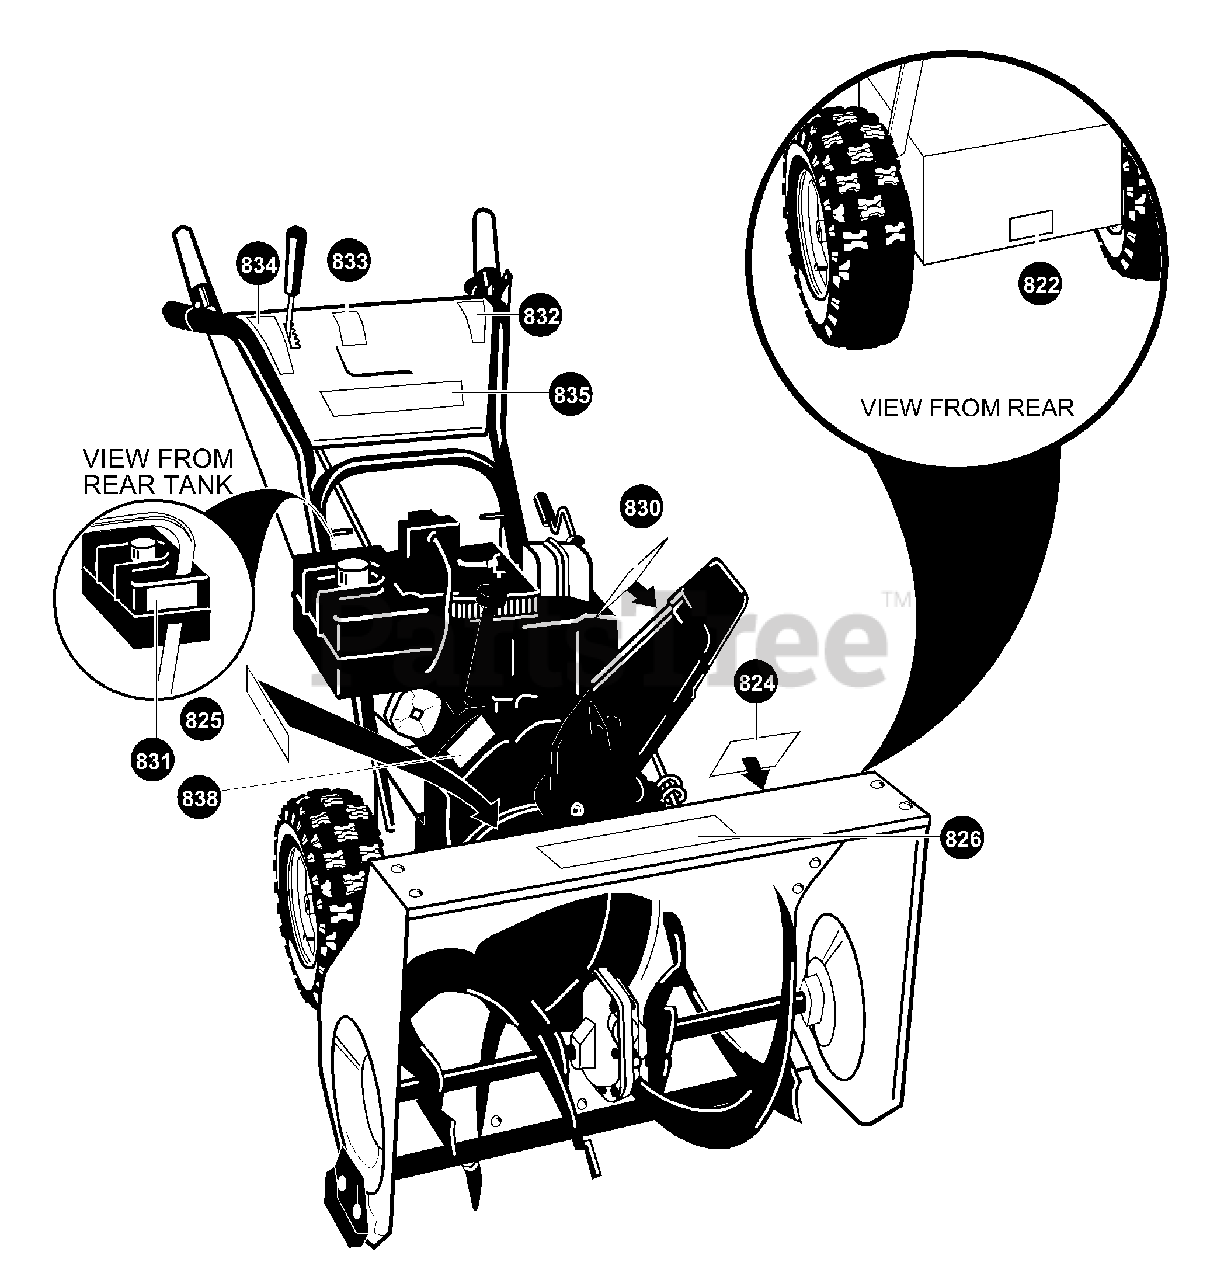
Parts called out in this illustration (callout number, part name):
822	DECAL, OVER ADJ OF DISC
824	DECAL, DANGER FOOT SYM
825	DECAL, DUAL STAGE
826	DECAL, AUGER HSING TOP
830	DECAL, DANGER FINGER
831	DECAL, FREE IMPELLER
832	DECAL, TRACT DR -CHUTE ROT
833	DECAL, SNOW CONDITIONS
834	DECAL, GEAR SELECT/AUGER
835	DECAL, HANDLE PANEL
838	DECAL, BELT ADJ.
